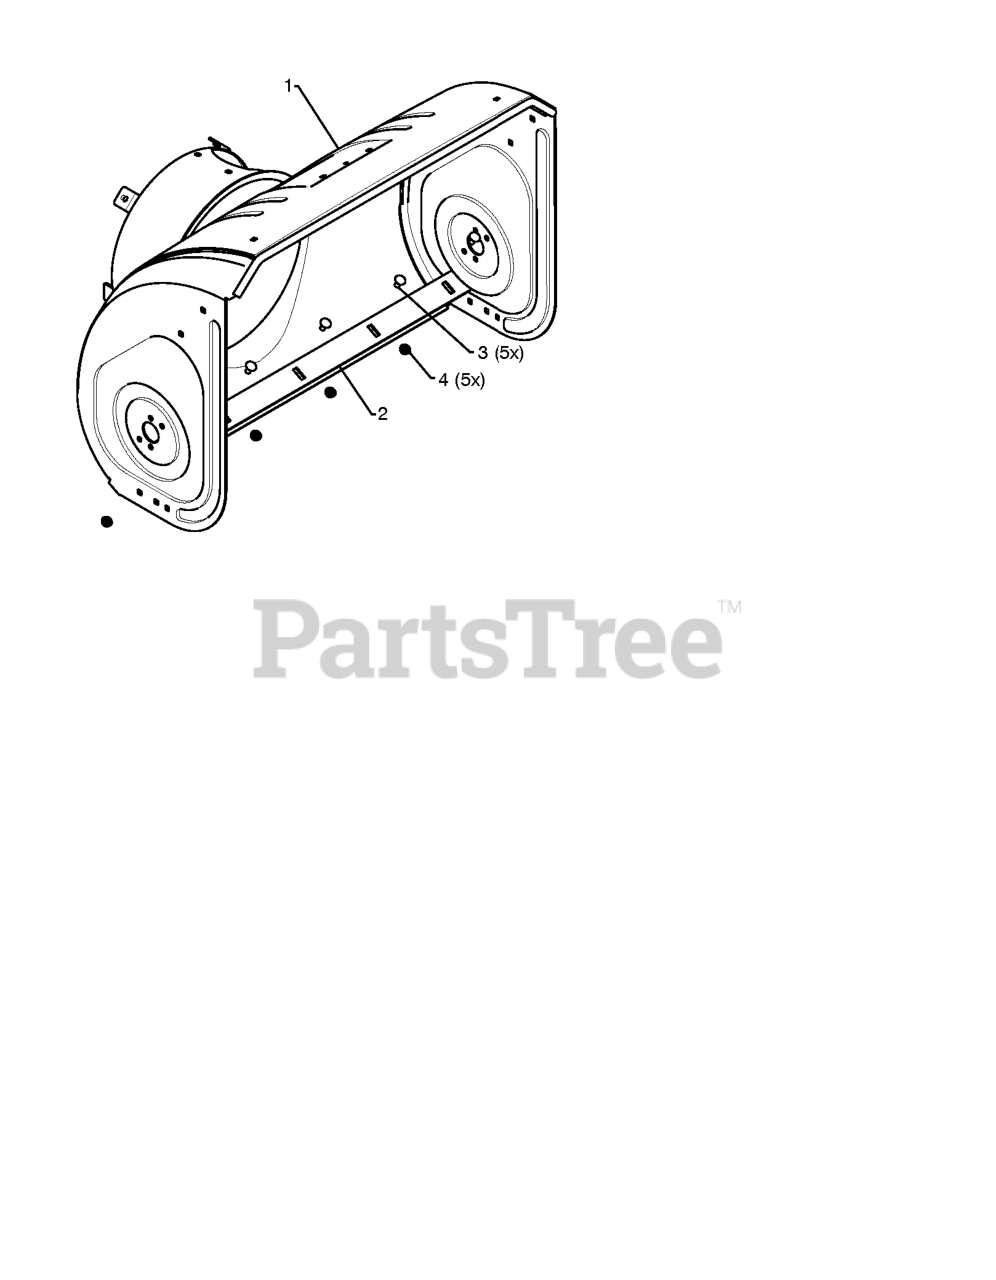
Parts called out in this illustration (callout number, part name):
1	HOUSING.AUG.WELDMENT.30.ORANGE
2	RP BAR.SCRAPER.30.BLACK
3	BOLT
4	NUT.FLANGE.5/16
